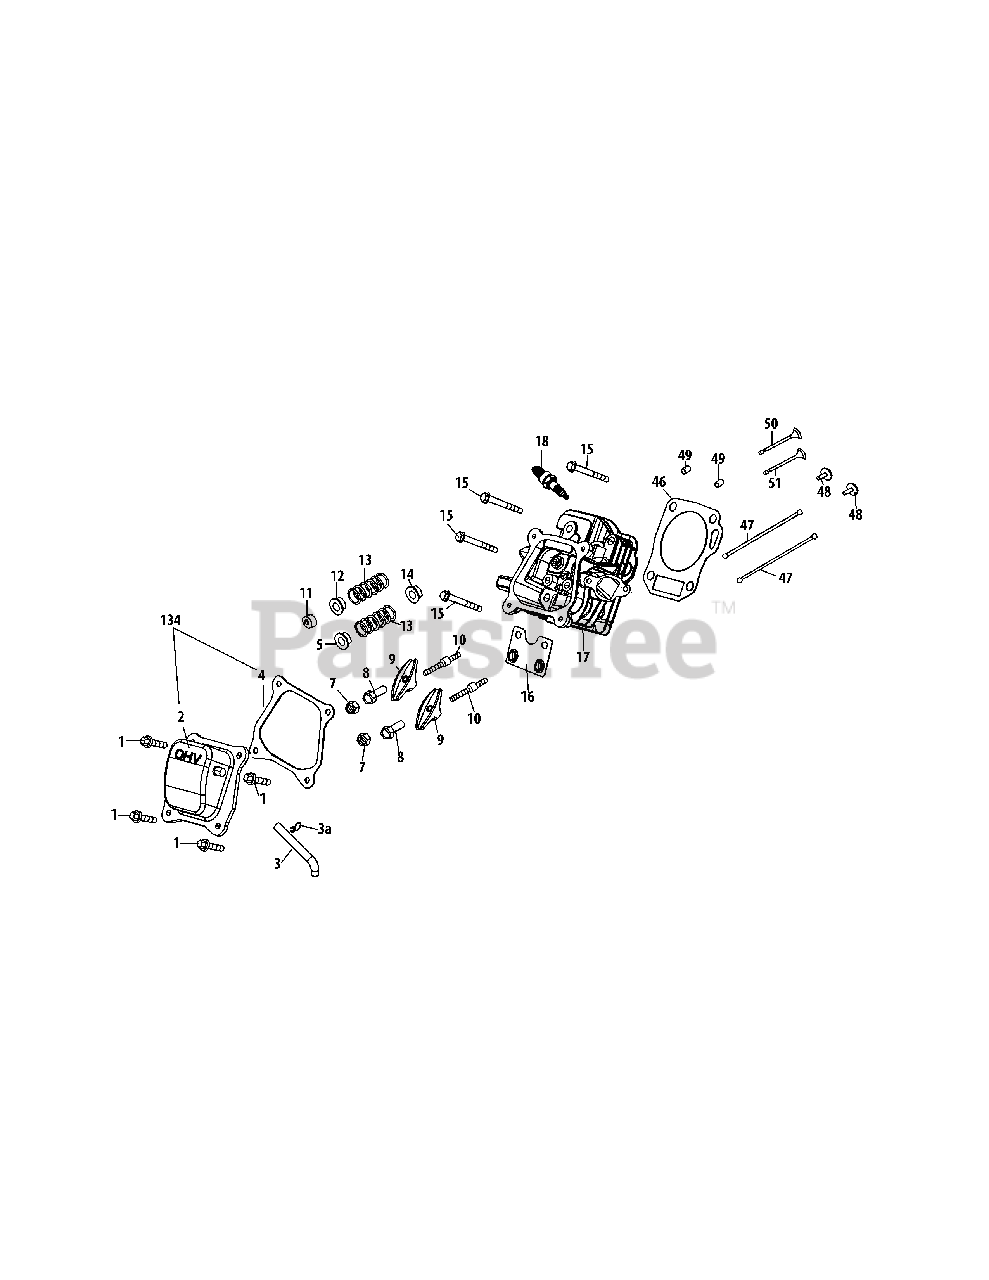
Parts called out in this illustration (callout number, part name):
1	Bolt M6×16
2	Valve Cover
3	Breather Hose
4	Valve Cover Gasket
5	Retainer, Intake Valve Spring
6	Rocker Arm Assembly
7	Nut, Pivot Locking
8	Adjusting Nut, Valve
9	Rocker Arm
10	Bolt, Pivot
11	Adjuster, Exh Valve
12	Retainer, Exhaust Valve Spring
13	Valve Spring
14	Intake Valve Seal
15	Bolt M8×55
16	Push Rod Guide
17	Cylinder Head Assembly
18	Spark Plug/F6Rtc
46	Gasket, Cylinder Head
47	Push Rod Kit
48	Tappet
49	Dowel Pin 10×16
50	Valve Kit
51	Valve Kit
134	Valve Cover Kit
